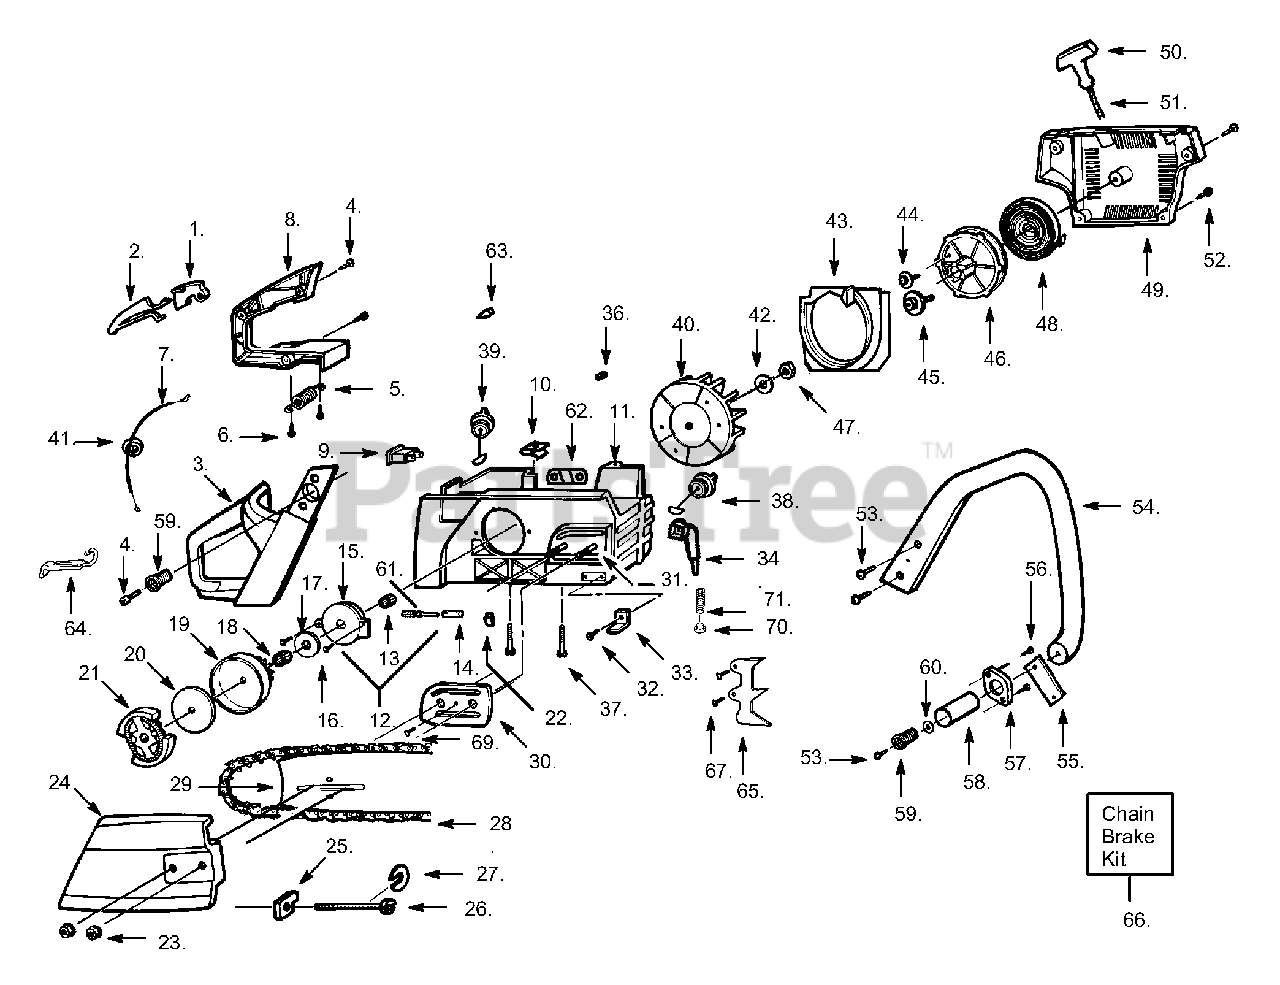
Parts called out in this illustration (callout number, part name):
1	Throttle Trigger
2	Throttle Lockout
3	Rear Pro Handle
5	Isolator Spring
7	Throttle Cable
8	Handle Cover
9	Ignition Switch
10	Speed Nut
11	Chassis Ass'y. 2200
11	Chassis Ass'y. 2500 & 2600
11	Chassis Ass'y. 2750, & 3050
12	Oil Pump Ass'y.
13	Oil Pump Worm
14	Oil Pump Barrel
15	Oil Pump Hsg.
17	Thrust Washer
18	Clutch Bearing
19	Clutch Drum 2200, 2500 & 2600
19	Clutch Drum 2750, & 3050
20	Clutch Washer
21	Clutch Ass'y.
22	Oil Seal
23	Bar Mounting Nut
24	Clutch Cover
25	Bar Adjusting Pin
27	Retainer-Bar Adjust
28	Chain 2200/2500/2600-16"
28	Chain 2200/2500/2600-18"
28	Chain 2750-18"
28	Chain 2750/3050-20"
29	Bar 2200/2500/2600-16"
29	Bar 2200/2500/2600-18"
29	Bar 2750-18"
29	Bar 2750/3050-20"
30	Bar Plate
31	Bar Bolt
33	Chain Catcher
34	Oil Pick-up
35	Oil Intake Screen
36	Vent Plug
38	Oil Cap Ass'y.
39	Fuel Cap Ass'y.
40	Flywheel Ass'y. All execpt 3050
40	Flywheel Ass'y. 3050
41	Grommet 2750 & 2500/2600-Type 1,2,3 & 4
41	Grommet 2200,2500/2600-Type 5 & 3050
43	Baffle Plate
46	Starter Pulley
48	Recoil Spring
49	Fan Hsg. Ass'y. Kit
50	Starter Handle All except 3050
50	Starter Handle 3050
51	Rope Kit
54	Handle All except 3050
54	Handle 3050
55	Front Strap
57	Isolator Plate
58	Spring Sleeve
59	Isolator Spring
61	Plunger & Gear Ass'y.
62	Bar Stud Plate
63	Check Valve
64	Choke Lever
65	Spike All except 3050
65	Spike 3050
66	Chain Brake Ass'y.
70	Plug-Oiler Filter
71	Oil Filter
